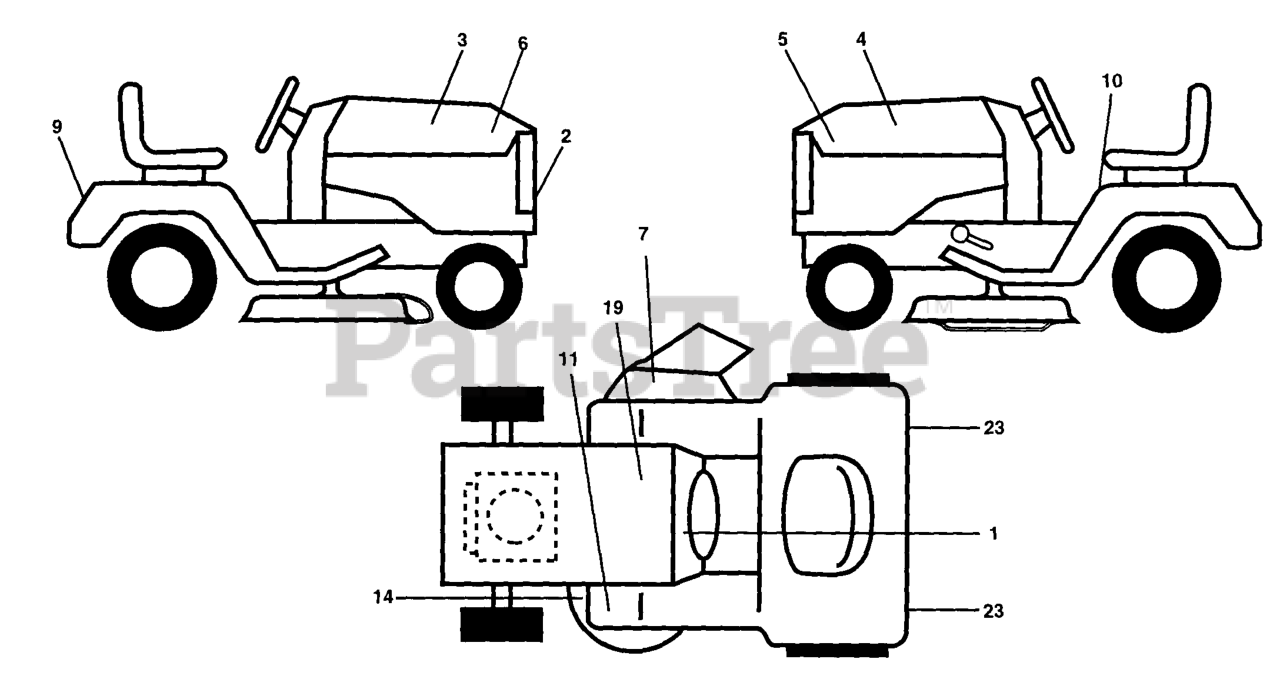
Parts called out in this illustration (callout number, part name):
2	DECAL GRILL HUSQ NLA
3	DECAL-HOOD R.H.
4	DECAL-HOOD L.H.
7	DECAL WARNING (ENGLISH/FRENCH)
9	DECAL FENDER NLA
10	DECAL CAUTION
23	REFLECTOR-TAIL YT
